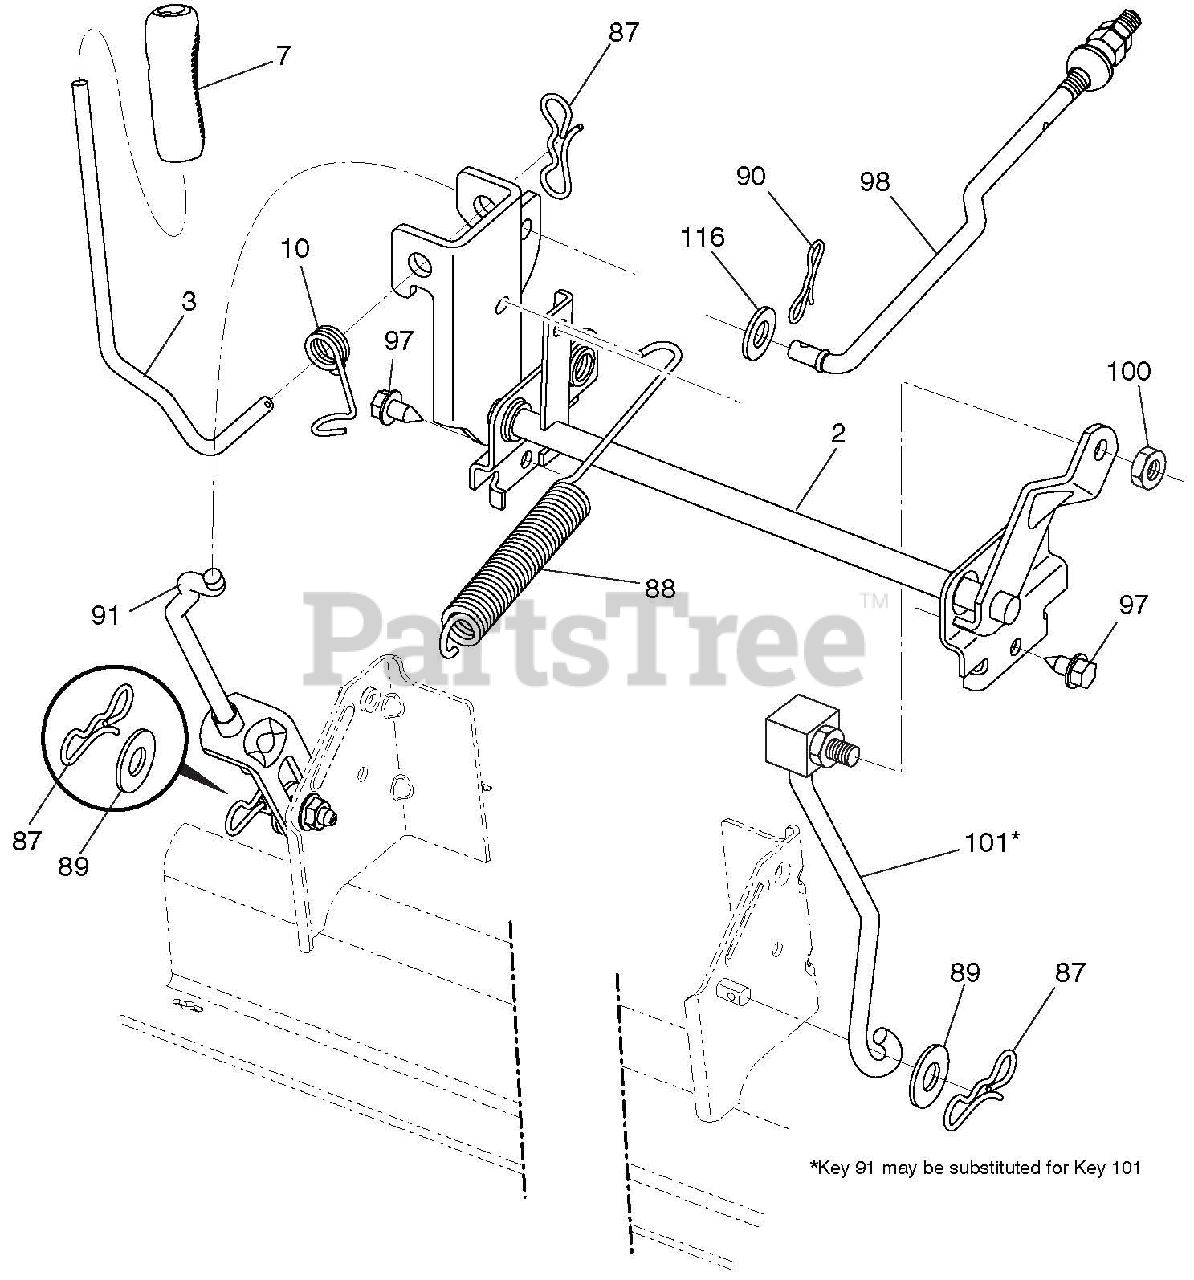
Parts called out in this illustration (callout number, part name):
2	SHAFT ASM., LIFT
3	LEVER.LIFT.HANDLE.LT
7	GRIP LEVER 5625 LD BLACK 428
10	SPRING.TORSION.HANDLE.LIFT
87	PIN.COTTER.7/16.BOW TIE LOCK
88	SPRING.LIFT ASSIST
89	WASHER.CLEAR ZINC
90	PIN.COTTER.5/16.BOW TIE LOCK
91	LINK ASM.LIFT.LH.REAR
97	SCREW.HEXWSH THDR3/8-16X3/4.BL
98	LINK ASM.SUSP.FRONT.MWR.11
100	NUT.CENTERLOCK.3/8-16 UNC.
101	LINK ASM.LIFT.FIXED.38/42/46"
116	WASHER 15/32 X 15/16 X 16 GA.
